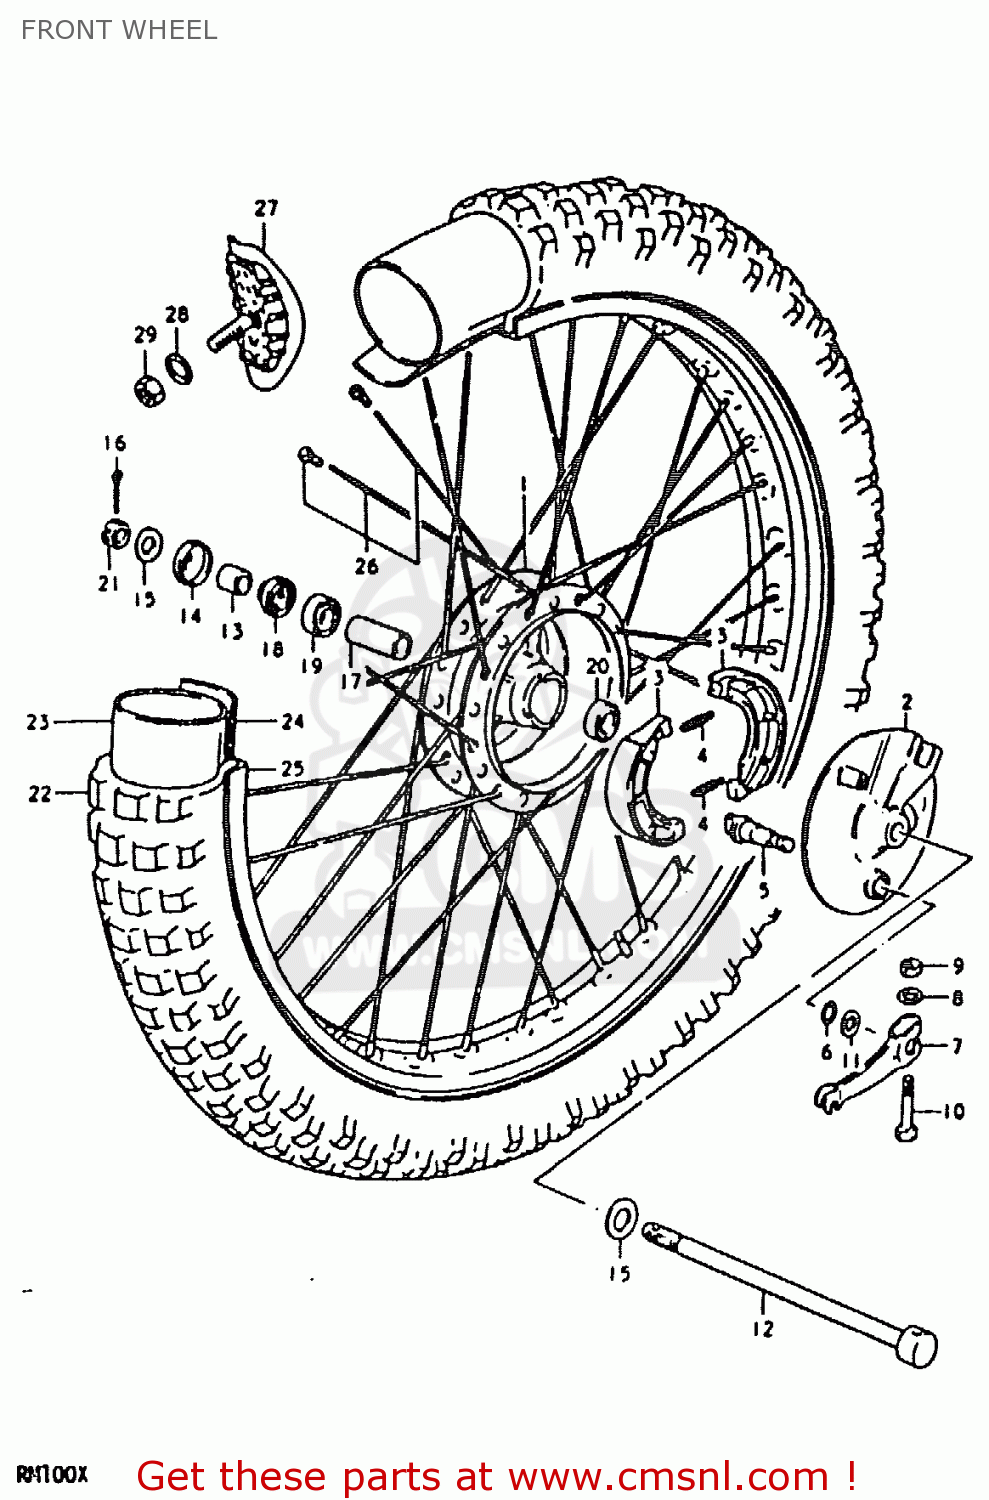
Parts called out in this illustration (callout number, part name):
1	HUB,FRONT
2	PANEL,FRONT HUB
3	SHOE,BRAKE
4	SPRING(L:34)
5	CAM,FR BRAKE
6	O RING(D:2.5,ID:11.4)
7	LEVER,FRONT BRAKE CAM
8	WASHER
9	NUT
10	BOLT
11	WASHER(12.5X20X1)
12	AXLE,FRONT
13	SPACER
14	DUST SEAL,FRONT HUB DRUM
15	WASHER
16	COTTER PIN
17	SPACER (12.6X19X52)
18	OIL SEAL
19	BEARING
20	BEARING
21	NUT 12MM
22	TIRE,FRONT
23	TUBE
24	PROTECTOR,WHEEL,INNER
25	RIM,FRONT WHEEL
26	SPOKE SET,FRONT
27	STOPPER,BEAD
28	WASHER
29	NUT
